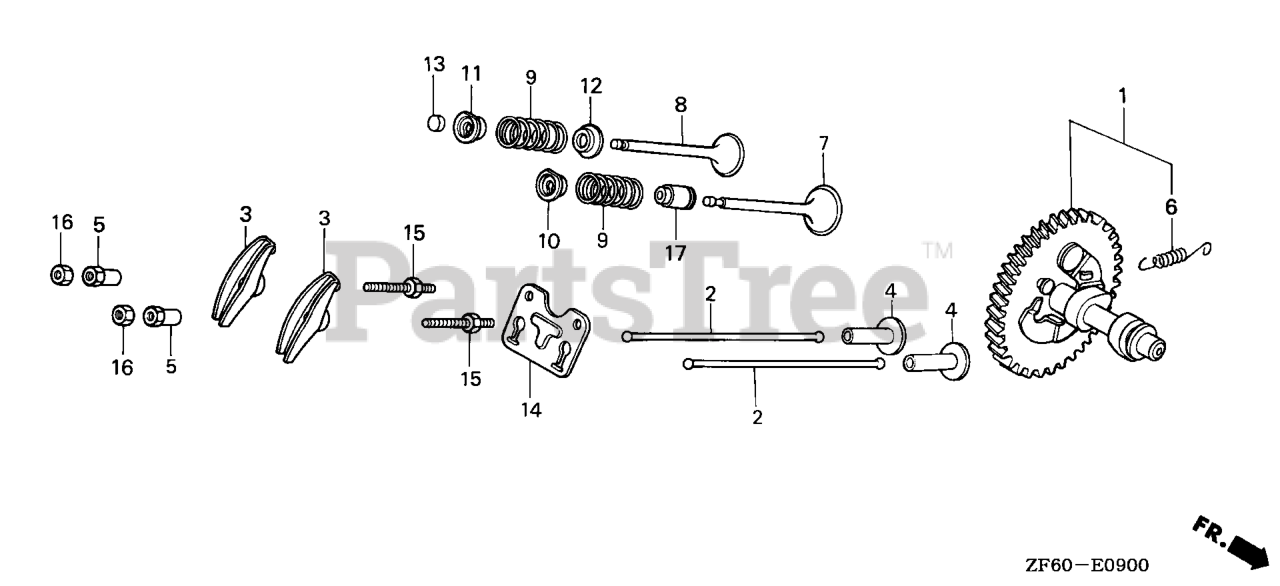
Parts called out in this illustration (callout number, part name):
1	CAMSHAFT ASSY.
2	ROD, PUSH
3	ARM, VALVE ROCKER
4	LIFTER, VALVE
5	PIVOT, ROCKER ARM
6	SPRING, WEIGHT RETURN
7	VALVE, IN.
8	VALVE, EX.
9	SPRING, VALVE
10	RETAINER, IN. VALVE SPRING (EXHAUST SIDE)
11	RETAINER, EX. VALVE SPRING
12	SEAT, VALVE SPRING
13	ROTATOR, VALVE
14	PLATE, PUSH ROD GUIDE
15	BOLT, PIVOT (8MM)
16	NUT, PIVOT ADJ.
